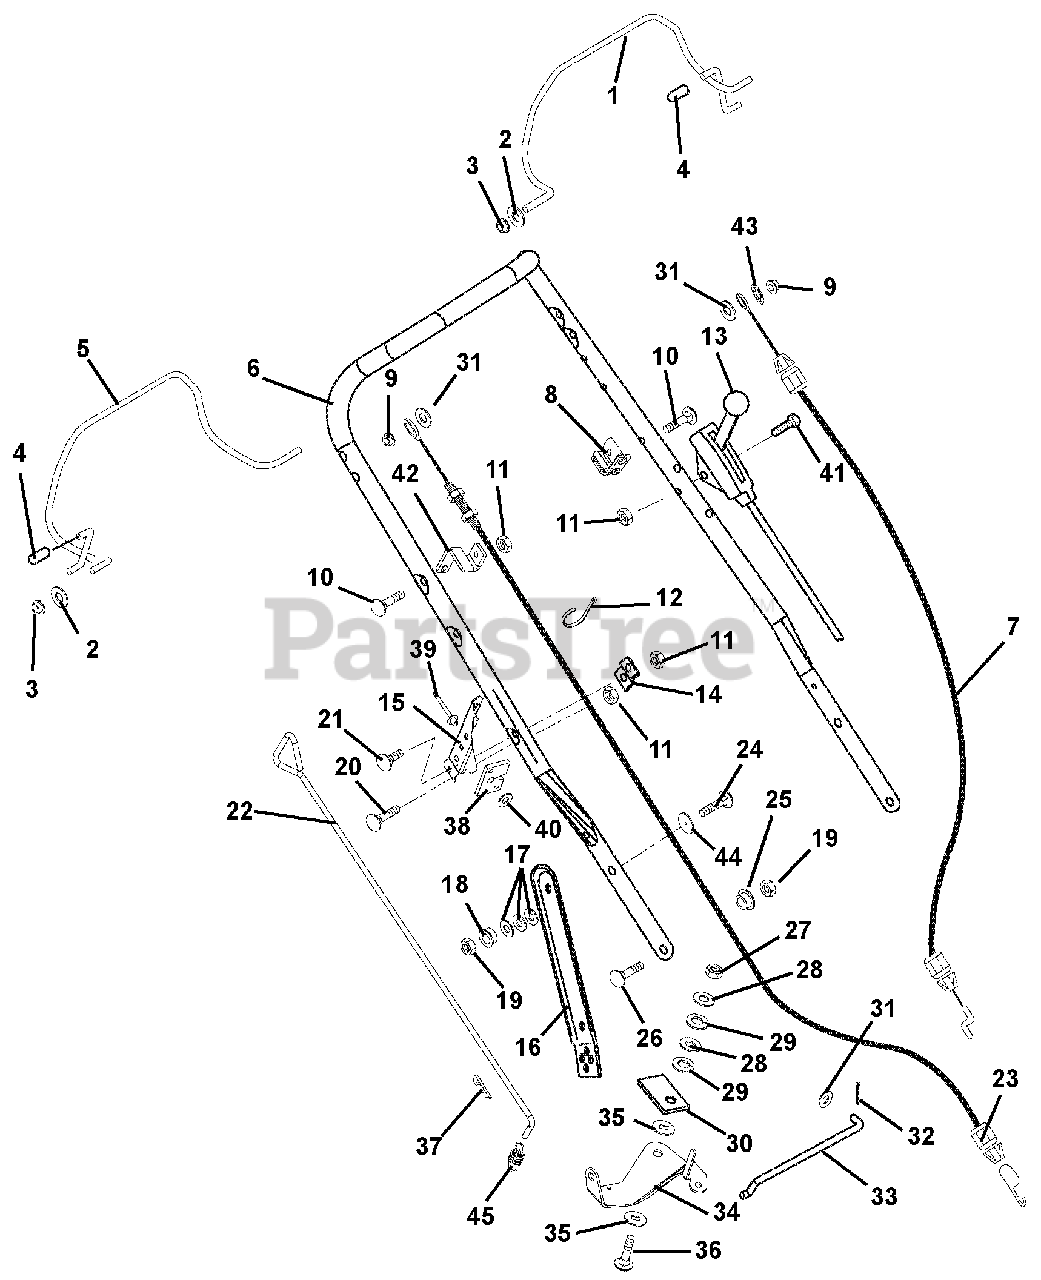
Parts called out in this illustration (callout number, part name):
1	Bail, Engine
2	Washer, Flat Steel .32 x .44 x .44 x .56 (911196, 197)
3	Bushing, Flange .325 x .688 x .560 (911196, 197)
4	Cap, Vinyl .25 I.D. (911196, 197)
5	Traction Bail (911196, 197)
6	Handlebar
7	Cable, Engine Kawasaki (911196, 171)
8	Cable, Anchor
9	Push Nut, .25 (911196, 197)
10	Bolt, Round Head Square Neck .25-20 x 1.25 (911196, 197)
11	Nut, Locking Center .25-20 (911196)
12	Cable Tie (911197)
13	Cable, Lockout Control (911197)
14	Brace, Speed Control
15	Bracket, Speed Control Slotted
16	Link, Handlebar Adjuster Left Hand
17	Washer, Bellville Spring
18	Bushing, Flange .325 x .50 x .513 x .875
19	Nut, Locking Center .31-18
20	Bolt, Round Head Square Neck .25-20 x 1.38 Grade 5
21	Bolt, Round Head Square Neck .25-20 x .50 Grade 5
22	Rod, Speed Control (911196, 197)
23	Traction Cable (911196, 197)
24	Bolt, Round Head Square Neck .31-18 x 1.00 Grade 5
25	Shoulder Spacer
26	Bolt, Round Head Square Neck .31-18 x .75 Grade 5
27	Nut, Locking Center .38-16 (911196, 197)
28	Washer, Flat Steel .406 x .812 x .065 (911196, 197)
29	Washer, Lock .375 x .115 Heavy (911196, 197)
30	Pressure Flange (911196, 197)
31	Washer, Flat Steel .281 x .62 x .065 (911196, 197)
32	Pin, Cotter .06 x .50 (911196, 197)
33	Shift Link (911196, 197)
34	Bell Crank, Speed Control (911196, 197)
35	Friction Washer (911196, 197)
36	Bolt, Round Head Square Neck .38-16 x 1.25 (911196, 197)
37	Pin, Hair Internal .08 x .18 x 1.18 (911196, 197)
38	Pad, Rubber Support (911196, 197)
39	Rivet .187 x .575 (911196, 197)
40	Washer, Flat Steel .219 x .50 x .049 (911196, 197)
41	Bolt, Round Head Square Neck .25-20 x 2.00 Grade 5 (911197)
42	Anchor, Cable (911196, 197)
43	Ring, Retaining External (911171)
44	Washer, Flat Steel .505 x .880 x .072
45	Spring, Extension (911196, 197)
